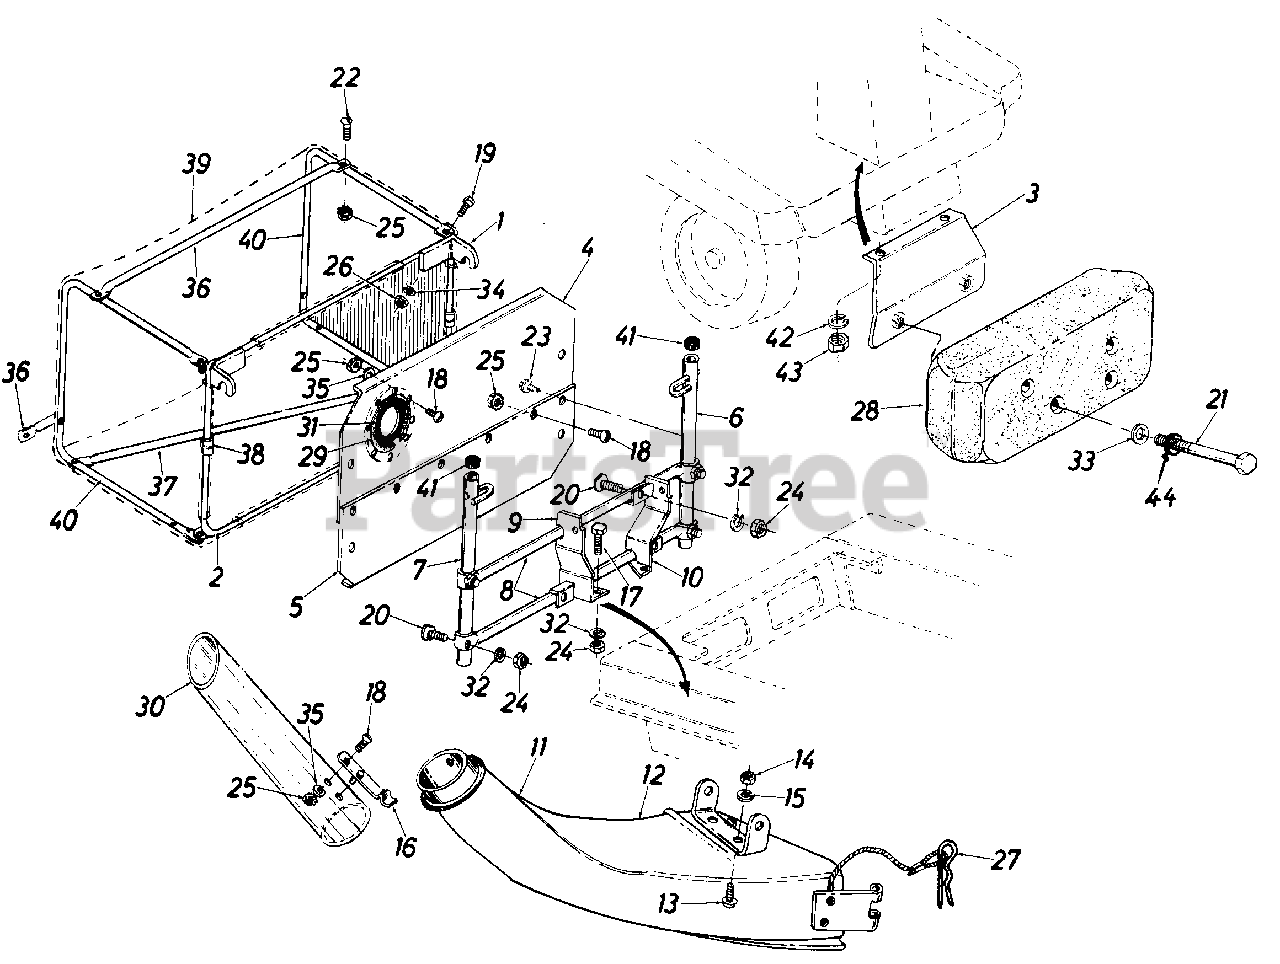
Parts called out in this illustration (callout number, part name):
1	Catcher Frame Ass'y.-Upper
2	Catcher Frame Ass'y.-Lower
3	Counterweight Support Bracket. Ass'y.
4	Front Cover-Upper Half
5	Front Cover-Lower Half
6	L.H. Vertical Support Ass'y.
7	R.H. Vertical Support Ass'y.
8	Horizontal Support Tubing
9	Catcher Support Brkt. Ass'y.-R.H.
10	Catcher Support Brkt. Ass'y.-L.H.
11	Discharge Chute Ass'y.
12	Brkt. Chute Hinge
13	Carr. Bolt 1/4-20 x .62" Lg.
14	Hex Nut 1/4-2 Thd.*
15	L-Wash. 1/4" I.D.*
16	Spring Lock Ass'y.
17	Hex Bolt 5/16-18 x .75" Lg. *
18	Truss Mach. Scr. #10-24 x.38" Lg. *
19	Hex Bolt 1/4-20 x .62" Lg.*
20	Curved Carr. Bolt 5/16-18 x 1.75" Lg.
21	Hex Bolt 3/8-16 x 4.50" Lg.*
22	Truss Mach. Scr. #10-24 x 1.0" Lg. *
23	Hex Wash Hd. AB-Tap Scr. 1/4" x.62" Lg.
24	Hex Nut 5/16-18 Thd.*
25	Hex Sems Nut #10-24 Thd.
26	Hex Nut 1/4-2 Thd.*
27	Internal Cotter Pin
28	Counter Weight-38#
29	Trim Strip-24"
30	Grass Chute Tube
31	Rubber Flap
32	L-Wash. 5/16" I.D. *
33	F lat Washer 3/8" I.D. x 1. 25" O.D. x .17
34	L-Wash. 1/4" I.D.*
35	Fl-Wash. .203" I.D. x .41" O.D. x .040
36	Grass Catcher Handle
37	Grass Catcher Handle
38	Tubing Connector 1/2" I.D.
39	Grass Bag
40	Catcher Side Frame
42	L-Wash.5/16" I.D.*
43	Hex Nut 5/16-18 Thd.*
44	Bell-Wash. 3/8" I.D. x 7/8" O.D.
